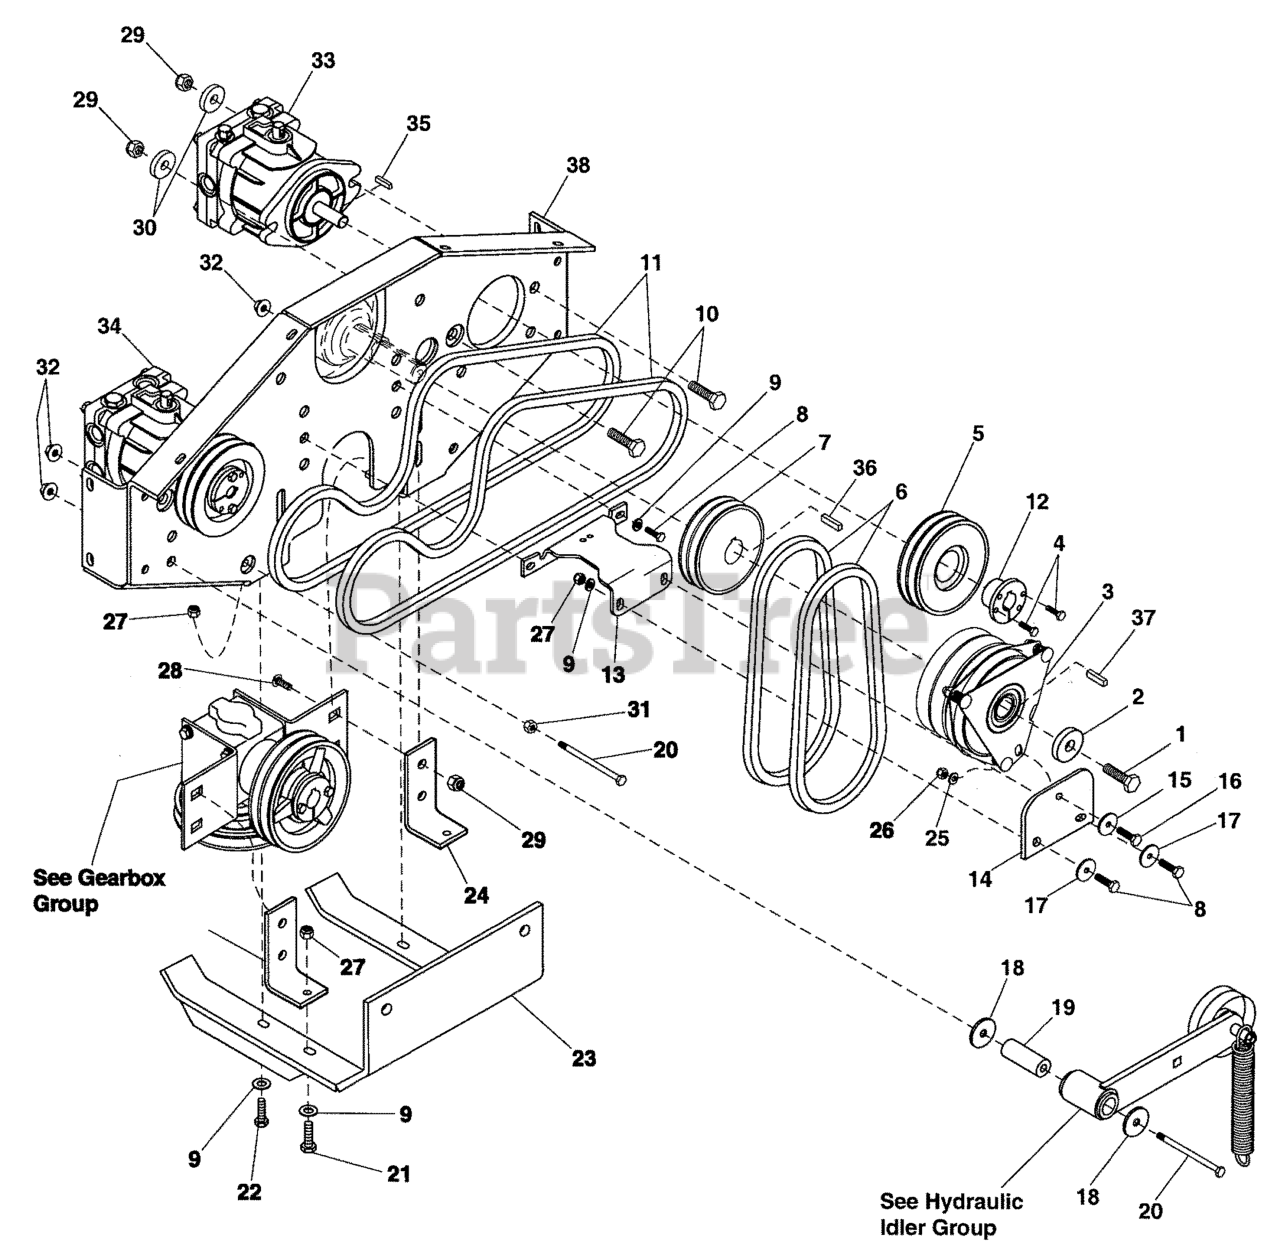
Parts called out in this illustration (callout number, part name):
1	BOLT, 7/16-20 x 2-1/2
2	CLUTCH RETAINER
3	KIT, CLUTCH & BOLT
4	BOLT, 1/4-20 X 1" GD5 CZ
5	PULLEY, Pump
6	BELT, PTO
7	PULLEY, Crank Shaft
8	BOLT, 3/8-16 X 1" GD5 CZ
9	WASHER, 3/8 SAE
10	BOLT, 1/2-20 X 1-3/4" GD8 CZ
11	BELT, Hydraulic
12	BUSHING, Tapered Hub
13	ANTI-ROTATION BRACKET
14	CLUTCH ANCHOR PAD
15	WASHER, Fender, 5/16
16	BOLT, 5/16-18 X 1 GD5 YZ
17	WASHER, Fender, 3/8
18	WASHER, Idler Arm Retaining
19	SPACER, .39 X 1.00 X 2.55, SS
20	BOLT, 3/8-16 X 4" GD5 CZ
21	BOLT, 3/8-16 X 1-1/2" GD5 CZ
22	BOLT, 3/8-16 X 1-1/4" GD5 CZ
23	SKID PLATE
24	SPRING MOUNT TAB
25	WASHER, 5/16" SAE
26	NUT, Hex, Nylon Lock, 5/16-18
27	NUT, 3/8-16 HEX NYLON LOCK
28	BOLT, Carriage, 1/2-13 x 1-1/2
29	NUT, 1/2-13 HEX NYLON LOCK
30	WASHER, Frame Retaining
31	NUT, 3/8-16 HEX JAM
32	NUT, Serrated Flange, 3/8-16
33	PUMP, Hydraulic, Right
34	PUMP, Hydraulic, Left
35	KEY, 5mm SQ.. x 25mm
36	KEY, 1/4 SQ.. x 1
37	KEY, 1/4 SQ.. x 2
38	PUMP PLATE
